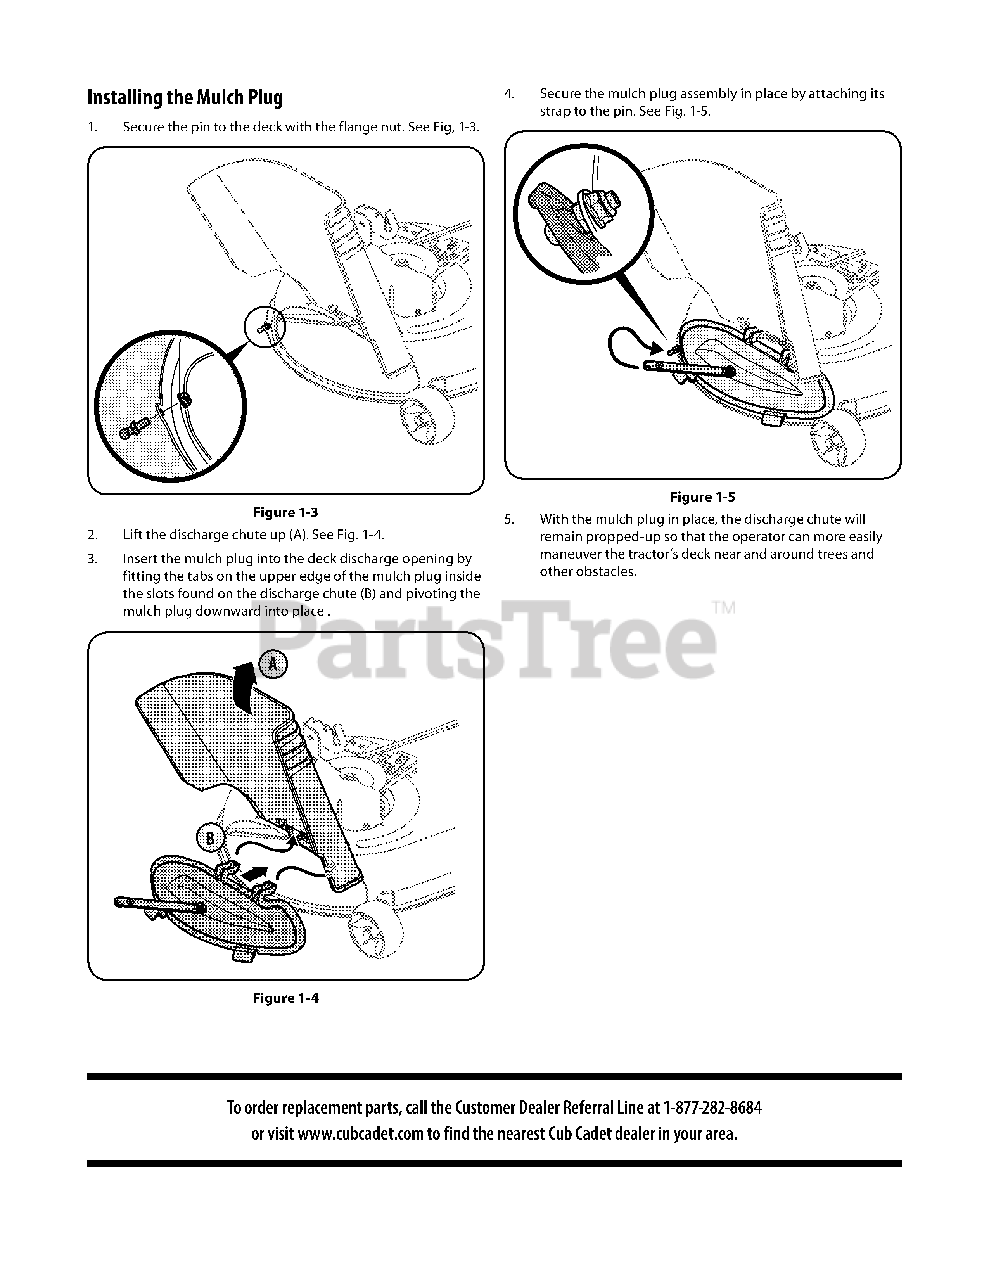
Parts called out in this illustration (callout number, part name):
1	Blade, 21.20
2	Plug, Mulch Assy 42"
3	Pin, Grasscatcher
4	Nut, Flange
